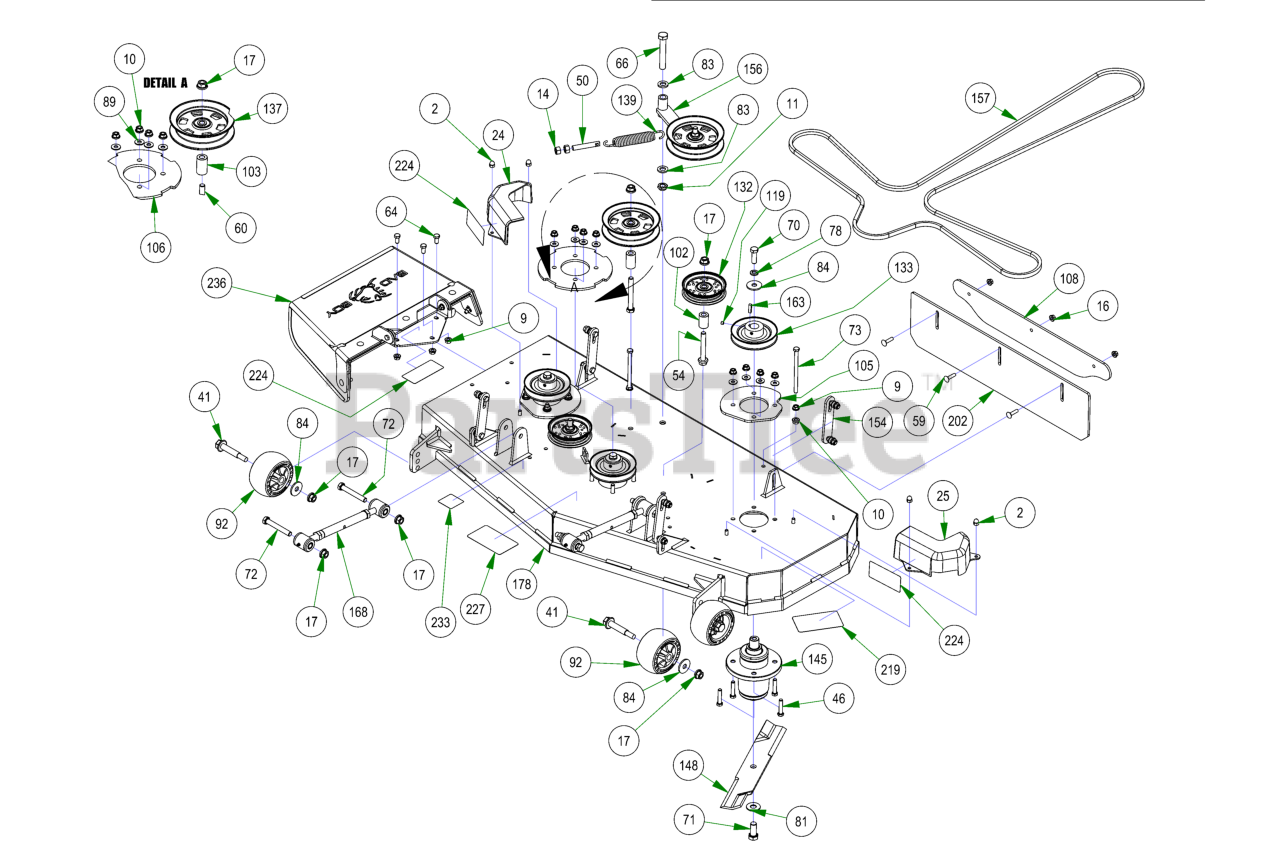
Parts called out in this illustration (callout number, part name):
2	5/16-18 ACORN NUT HIGH-CROWN ZC
9	3/8-16 HEX SERRATED FLANGE NUT HARD/ZINC
10	3/8-16 NYLON INSERT FLANGE LOCKNUT (GR.F) ZINC
11	5/8-11 NYLON INSERT JAM LOCKNUT ZINC
14	1/2-13 HEX NUT ZINC
16	5/16-18 NYLON INSERT FLANGE LOCKNUT ZINC
17	1/2-13 NYLON INSERT FLANGE LOCKNUT ZINC
24	pulley cover chute side
25	pulley cover non-chute side
41	Deck Wheel Bolt
46	3/8-16 X 1-3/4 HEX C/S (GR.5) ZC
50	All Thread
54	1/2-13 X 3-1/2 HEX FLANGE BOLT (GR.8) ZINC
59	5/16-18 X 1-1/4 CARRIAGE BOLT ZINC
60	1/2-13 X 4 HEX CAP SCREW (GR.8) ZINC YELLOW
64	3/8-16 X 3/4 HEX CAP SCREW (GR.5) ZINC
66	5/8-11 X 4 HEX CAP SCREW (GR.8) ZINC YELLOW
70	1/2-20 X 1-1/2 HEX CAP SCREW (GR.5) ZINC
71	5/8-18 X 1-1/2 HEX CAP SCREW (GR.8) ZINC YELLOW
72	1/2-13 X 3-1/2 HEX CAP SCREW (GR.5) ZINC
73	3/8-16 X 5-1/2 HEX CAP SCREW (GR.5) ZINC
78	1/2 SPLIT LOCKWASHER (GR.8) ZINC/YELLOW
81	5/8 USS FLAT WASHER (1-3/4" OD) GR.8 ZINC YELLOW
83	.635 ID X 1.120 OD X .140 THICK FLAT WASHER NYLON
84	1/2 BELLEVILLE WASHER (1-5/8 OD X .140 THK) ZINC
89	5/16 USS FLAT WASHER (7/8 OD) ZINC
92	Deck Wheel
102	.502 ID X .750 OD X 1.500 Long Spacer
103	1 3/4" Pulley Spacer
105	42&48 Deck Spindle Support Plate
106	Deck Spindle Support Plate
108	2023 4" & 5" Stripping Kit Plate
119	5/16-24 X 1/4 SOCKET SET SCREW (CUP PT) PLAIN
132	4 3/4 Idler Pulley - ABFI-76
133	5" Spindle Deck Pulley
137	5-3/4 Idler Pulley
139	Deck Idler Spring
145	OUTLAW SPINDLE ASSEMBLY
148	48" ZT/Mav/Compact Outlaw Blade with Fusion
154	Deck Hanger Assembly
156	2017 MZ/ZT Deck Idler Assembly
157	B147 Deck Belt
163	1/4 X 1 SQ MACHINERY KEY 1018 STL PLN
168	2018 Maverick Turnbuckle (Top Link)
178	2023 48" x 5" Deck
202	2023 ZT Stripping Kit Rubber
219	2018 48" Deck Decal
224	Danger Decal-Spindle/Discharge
227	Deck Belt Route Decal
233	Deck Impact Patent Decal 9591803
236	ZT Chute Assembly
